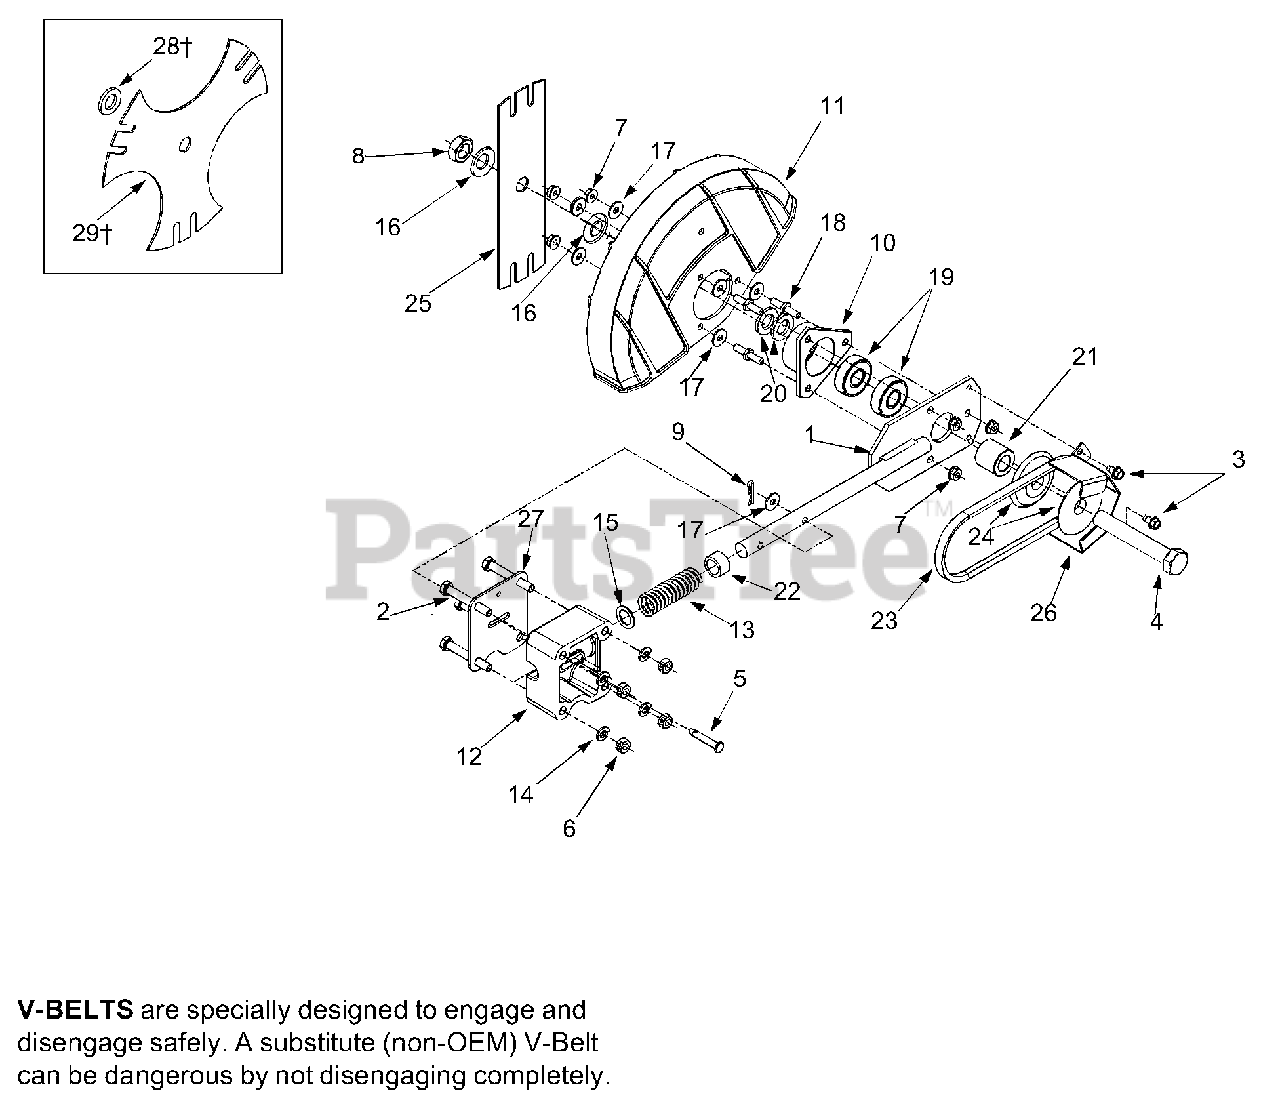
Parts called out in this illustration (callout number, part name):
1	Blade Plate Assembly
2	Hex Screw, 5/16-18
3	Self-tapping Screw, 1/4-20
4	Hex Screw, 5/8-18
5	Clevis Pin
6	Hex Lock Nut, 5/16-18
7	Hex Flange Nut, 1/4-20
8	Jam Nut, 5/8-18
9	Cotter Pin
10	Bearing Cup
11	Blade Guard
12	Bearing Block
13	Compression Spring
14	Lock Washer
15	Flat Washer
16	Bell Washer,.63 ID x 1.2 OD
17	Flat Washer,.260 x.72
18	Pin, 1/4-20
19	Bearing,.625 ID x 1.57 OD
20	Flat Washer
21	Spacer,.63 x 1.12 x 1.06
22	Spacer,.632 ID x.875 OD
23	Belt
24	Sheave
28	Flat Washer
